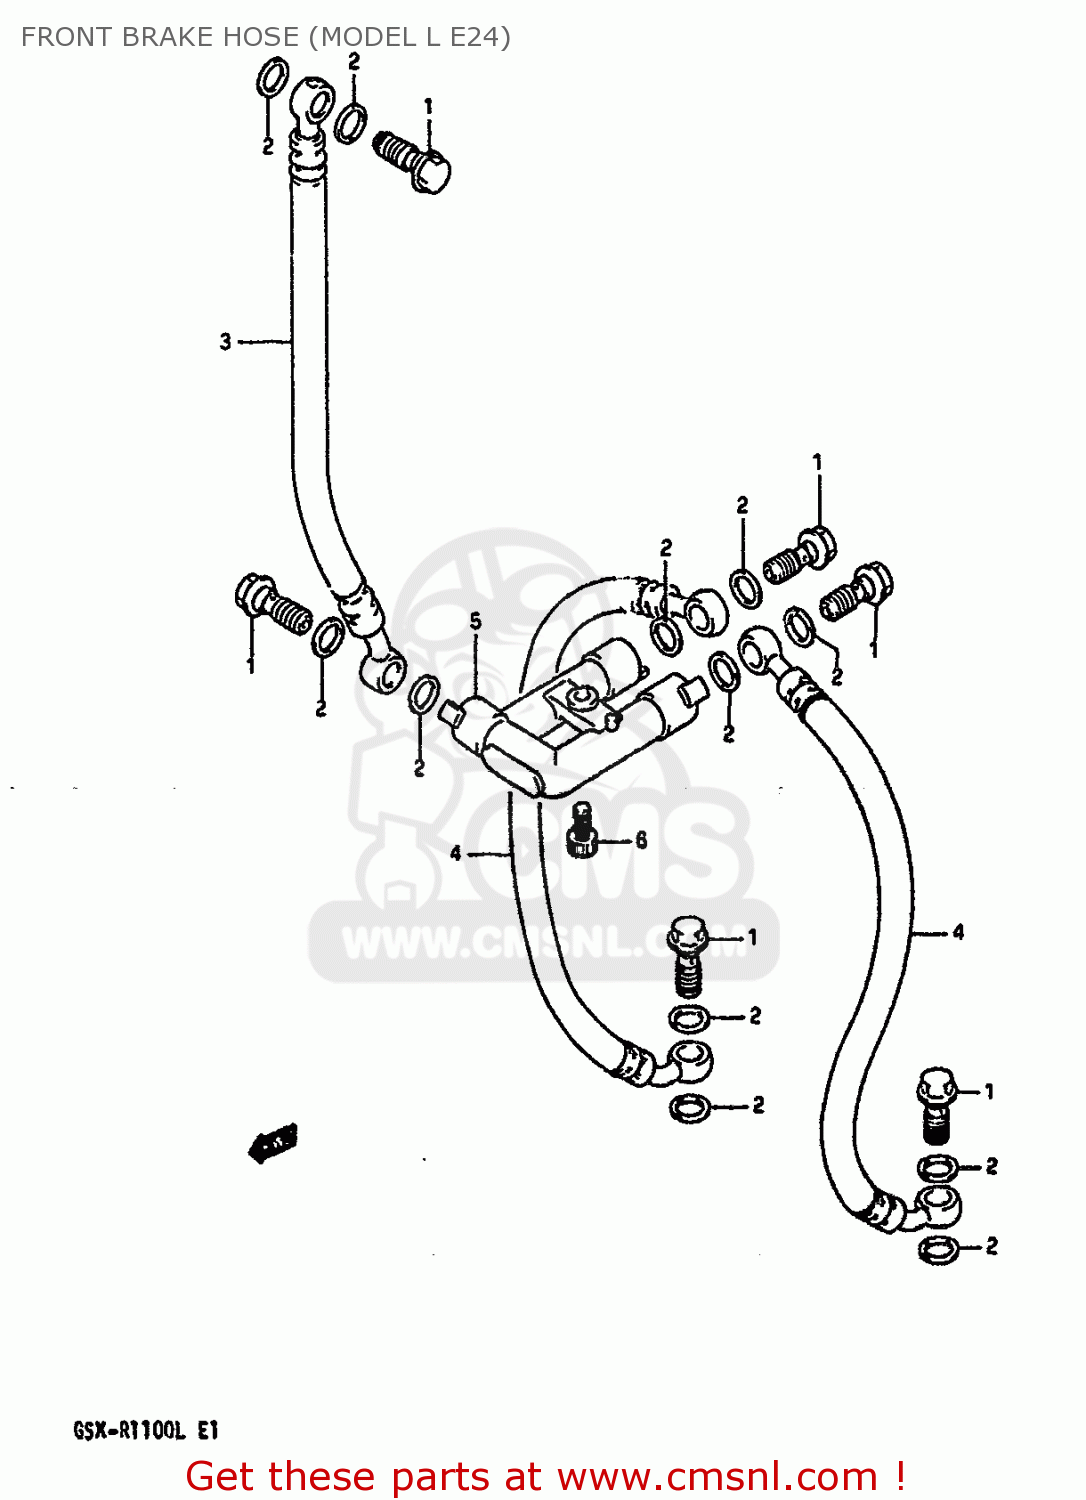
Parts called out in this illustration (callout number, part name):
1	BOLT UNION
2	WASHER(10X15X1.5)
3	HOSE COMP,FRONT BRAKE
4	HOSE,FR BRAKE NO.2
5	JOINT,BRAKE HOSE
6	BOLT
7	BOLT
